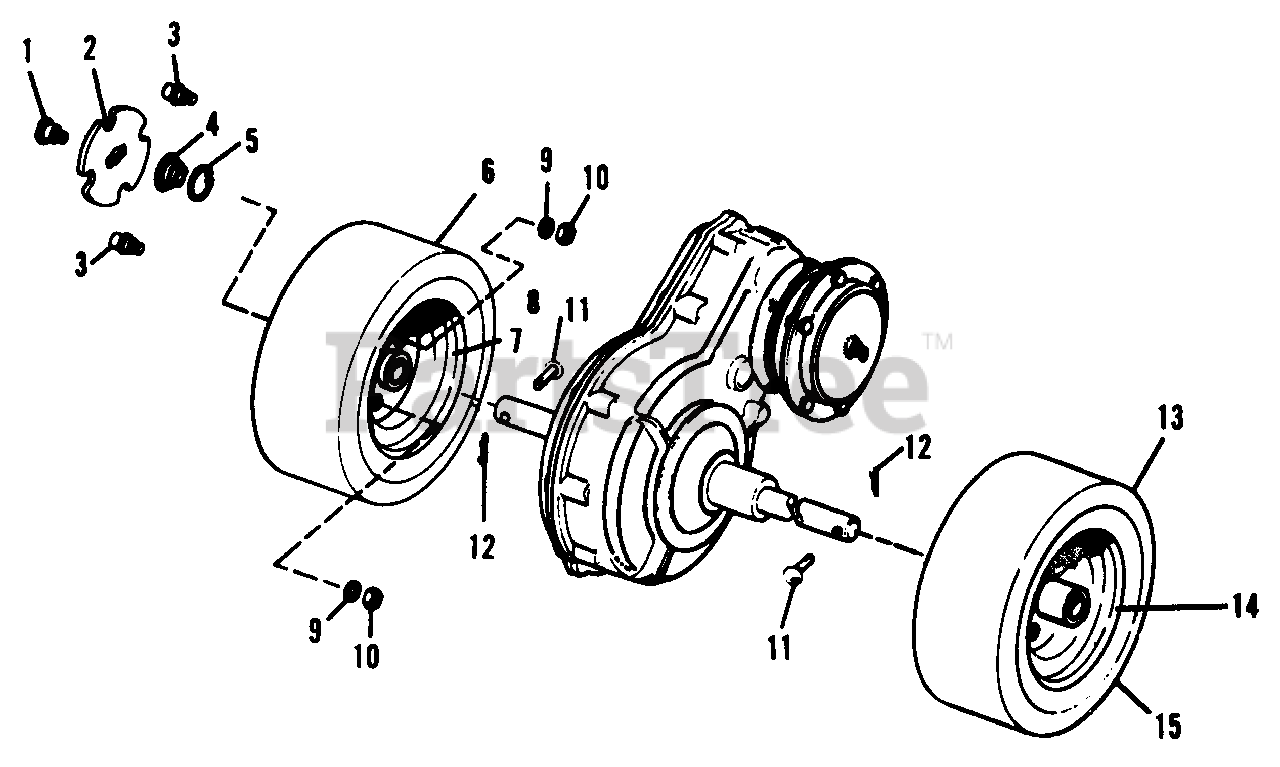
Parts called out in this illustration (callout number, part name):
1	BOLT-shoulder
4	SPRING
5	RING-retaining
6	WHEEL & TIRE ASSEMBLY-L.H.
7	WHEEL-L.H.
8	TIRE-5.30/44.50 x 6
9	WASHER-flat
10	NUT-full hex lock, 3/8-16
11	PIN
12	PIN-cotter, ext. prong
13	WHEEL & TIRE ASSEMBLY-R.H.
14	WHEEL-R.H.
15	TIRE-5.30/4.50 x 6
